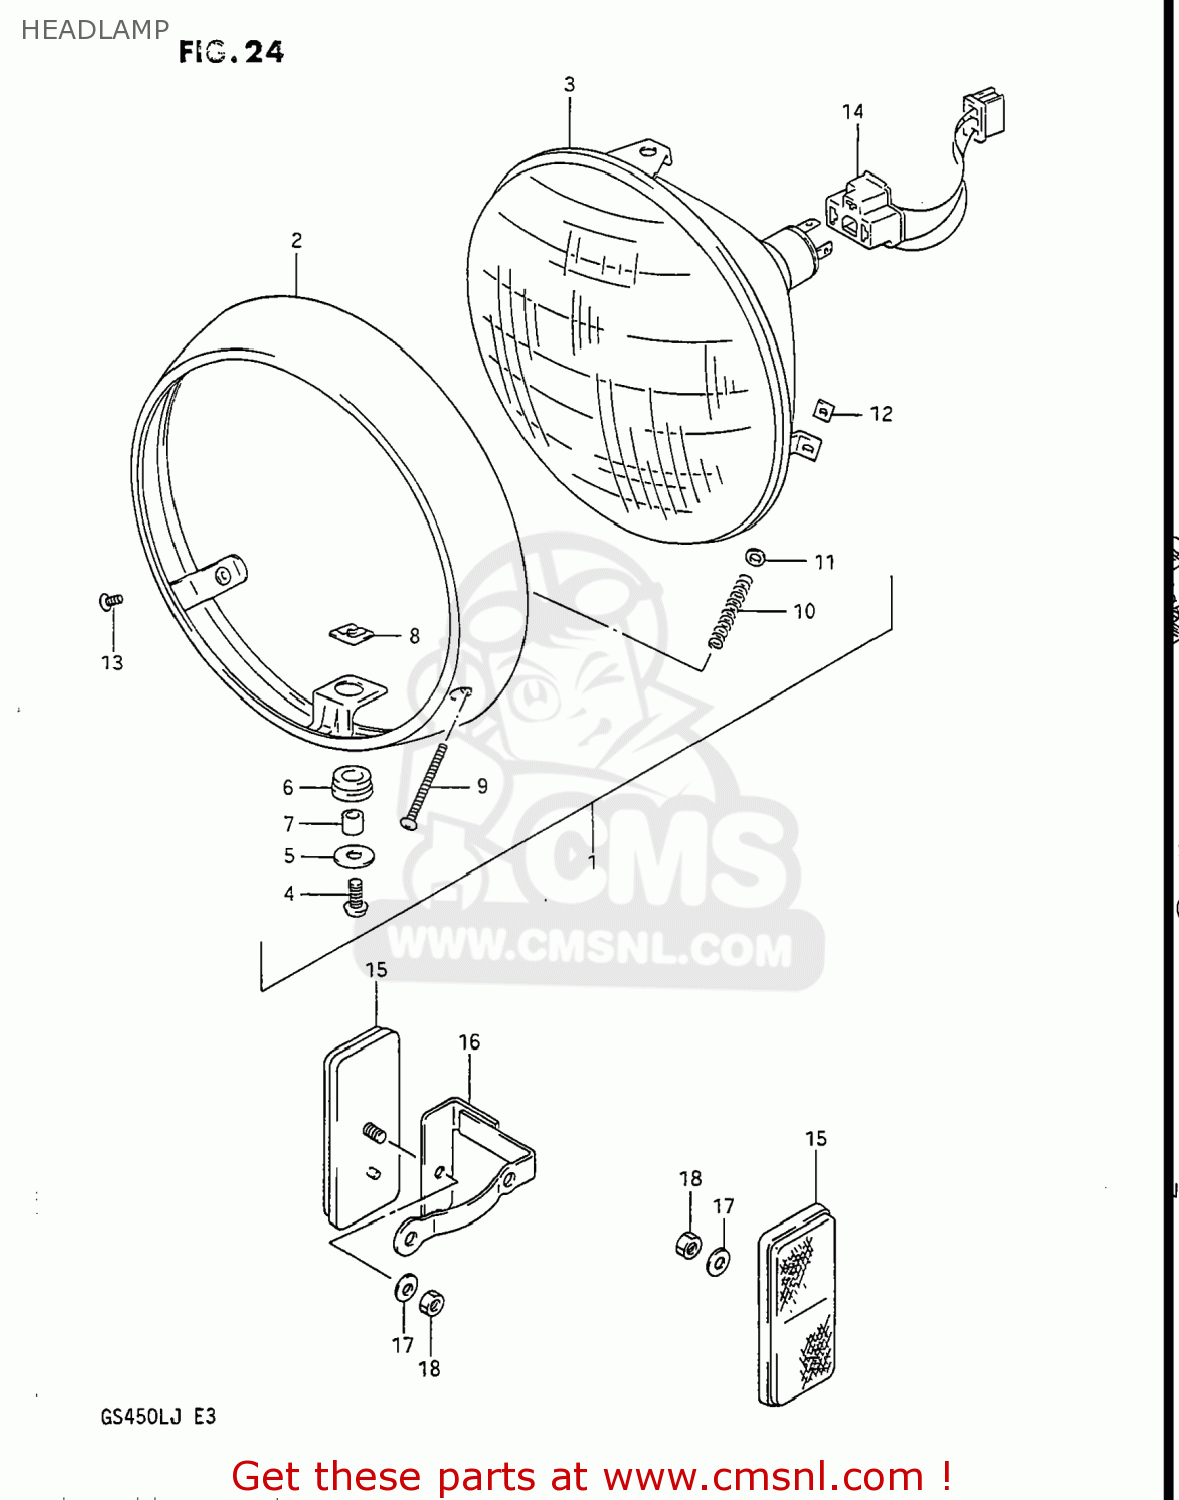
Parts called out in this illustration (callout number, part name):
1	LAMP ASSEMBLY,HEAD
2	RIM
3	LAMP UNIT
4	SCREW
5	WASHER
6	CUSHION
7	SPACER
8	NUT
9	SCREW
10	SPRING
11	WASHER
12	NUT,HEADLAMP ADJUSTER
13	SCREW(5X12)
14	LEAD WIRE,HEADLAMP
15	REFLEX REFLECTOR,FR SIDE
16	BRACKET,FRONT SIDE,REAR,RIGHT
17	WASHER,5MM
18	NUT ,5MM
